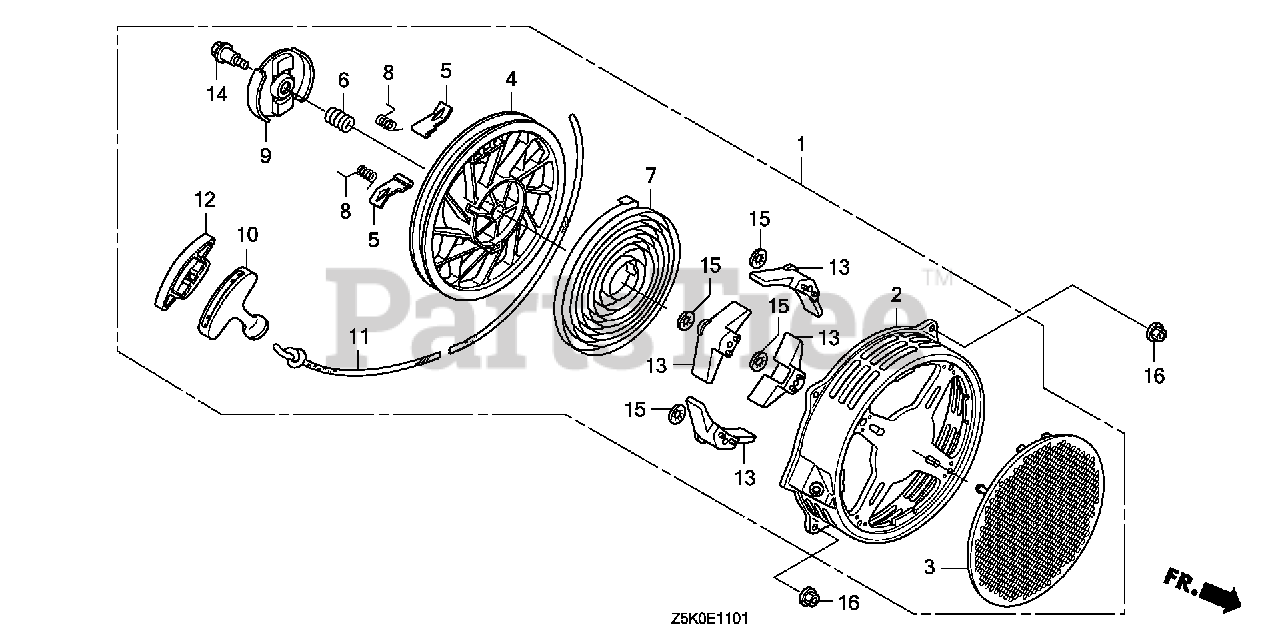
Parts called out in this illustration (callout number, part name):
1	STARTER ASSY., RECOIL *R280* (POWER RED)
1	STARTER ASSY., RECOIL *R280* (COO)(FOR U.S.A.) (POWER RED)
1	STARTER ASSY., RECOIL *NH1* (COO)(FOR U.S.A.) (BLACK)
2	CASE, RECOIL STARTER *NH1* (BLACK)
2	CASE, RECOIL STARTER *R280* (POWER RED)
3	COVER, RECOIL STARTER
4	PULLEY, RECOIL STARTER
5	RATCHET, STARTER
6	SPRING, FRICTION
7	SPRING, STARTER RETURN
8	SPRING, RATCHET
9	RETAINER, SPRING
10	GRIP, STARTER
10	GRIP, STARTER (COO)(FOR U.S.A.)
11	ROPE, RECOIL STARTER
12	GRIP, REINFORCEMENT
13	COVER, ROPE
14	SCREW, CENTER
16	NUT, FLANGE (6MM)
